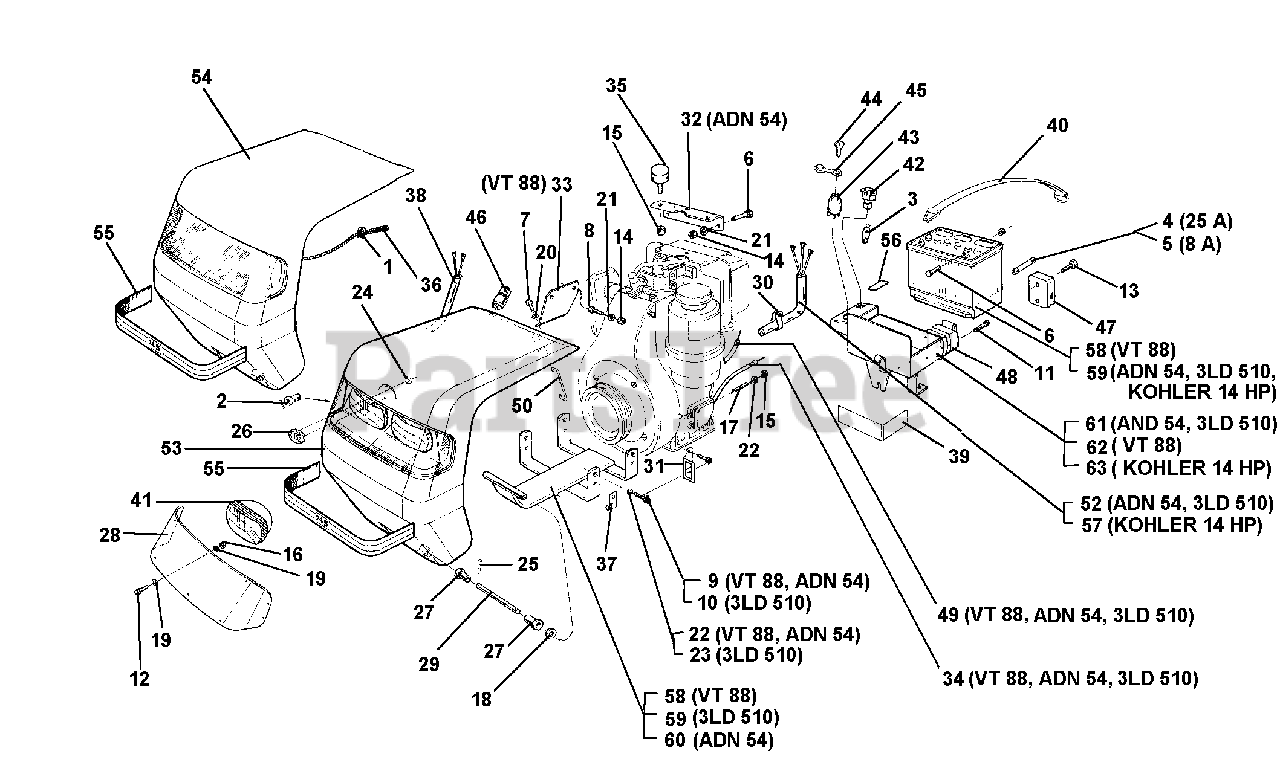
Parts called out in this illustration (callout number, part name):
1	CLAMP, CABLE 3/16
4	FUSE 6 X 25 25A
5	FUSE 6 X 25
6	SCREW TE M6 X 14
7	SCREW M6 X 25
8	SCREW TE M6 X 16
9	SCREW M8 X 20
10	SCREW TE M10 X 20 UNI 5739-8G
11	SCREW TCCEI M4 X 30
12	SCREW TC M4 X 16
13	SCREW TC M4 X 20
17	STUD M8 X 40 X 14 X 14
18	FLAT WASHER 10.5 X 21
20	SUPER WASHER 6 DIN 6796
21	WASHER, LOCK 6.4
22	WASHER, LOCK 8.4
23	WASHER, LOCK 10.5
24	WASHER, LOCK FOR PINS D-4
25	PIN, COTTER A 3 X 20 UNI 1336
28	WHITE TRANSPARENT PROTECTION
29	PIN, COUPLING
30	CLAMP ENGINE
32	TANK COUPLING
33	REGULATOR SUPPORT
34	CABLE & SHEATH,ACCEL.LOMBAR
36	COVER CABLE
37	SUPPORT, ACCELERATOR CABLE
38	WIRES LIGHTING SYSTEM COVER
39	ANTISHOCK BAT
40	BATTERY STRAP
41	FRONT LIGHT
42	WARNING LIGHT COBO 4706953
43	SWITCH EL. ST. COBO 14110100/1
44	KEY FLAT COBO 14109108
45	LOCK COVER OLSA 15651000
46	LIGHT SWITCH COBO 23101000
47	BOX FOR FUSES COBO 24021000
48	7-POLE SOCKET
49	SHEATH CABLE
51	ELECTRIC STARTER WIRES
52	ELECTRIC STARTER WIRING
53	LIGHTING SYSTEM COVER
54	ENGINE COVER
55	AUTOADHESIVE STRIP
57	KOHLER ELECTRIC STARTER CABLES
58	LOWER COUPLING
59	LOWER COUPLING
60	LOWER COUPLING
61	BATTERY BOX
62	BATTERY SUPPORT
63	KOHLER BATTERY SUPPORT
